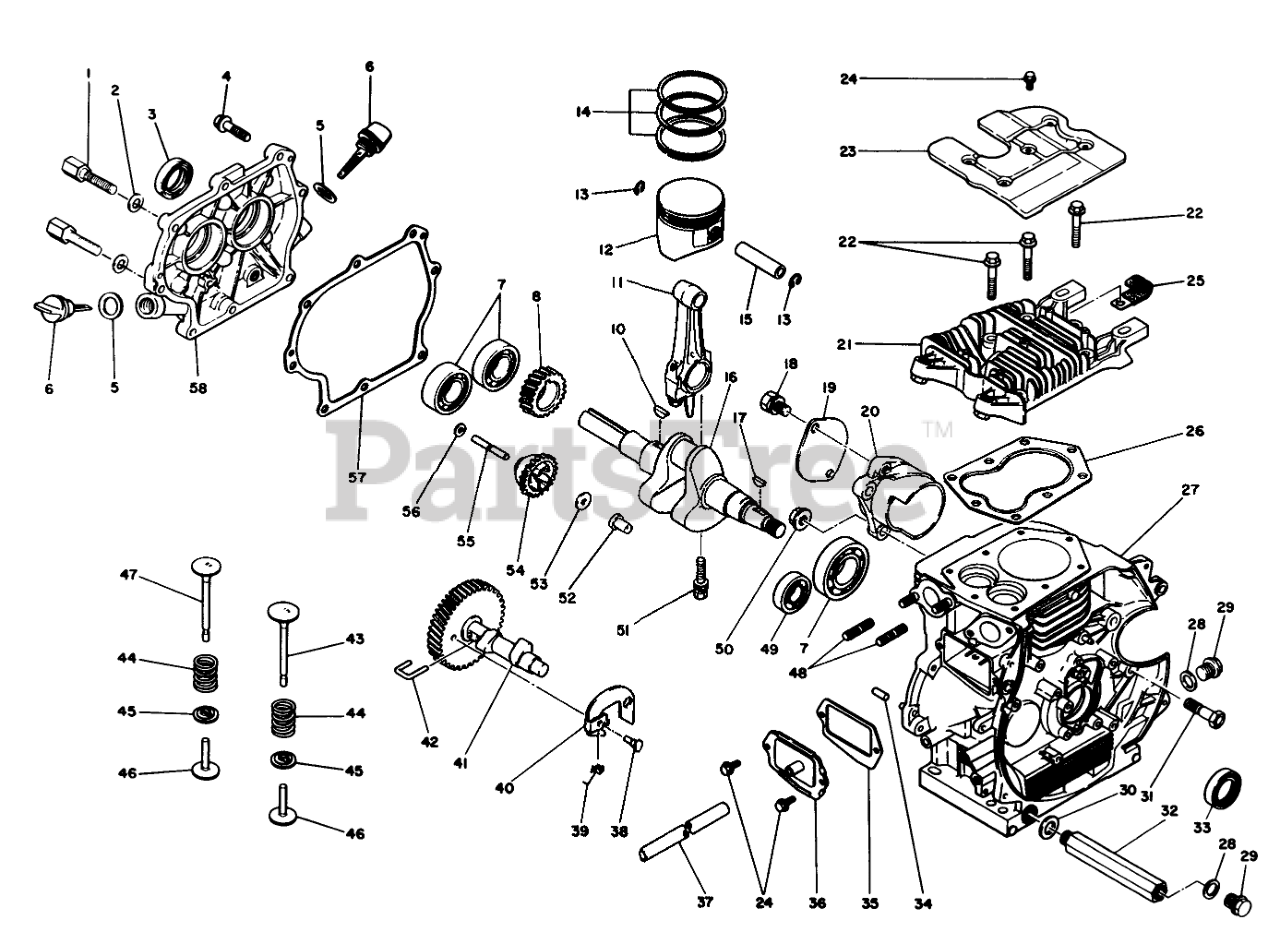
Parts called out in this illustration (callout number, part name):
2	WASHER
3	OIL SEAL
5	GASKET
6	Gauge-Oil (Incl. Ref. #5)
7	BEARING
8	CRANKSHAFT GEAR
11	Connecting Rod Assembly (Std.)(Incl. Ref #51)
12	Piston Assembly (Std.)(Incl. Ref. #15)
13	PISTON PIN CLIP
14	PISTON RING SET
15	PISTON PIN
16	CRANKSHAFT
18	BOLT & WASHER
19	COVER
20	BRACKET
21	CYLINDER HEAD
23	COVER-HEAD
25	CLAMP
26	HEAD GASKET
27	Cylinder Block Assembly (Incl. Ref. #34 & 48)
28	GASKET
29	DRAIN PLUG
30	GASKET
32	NIPPLE
33	OIL SEAL
35	GASKET=BRTHR
36	BREATHER VALVE ASM
37	BREATHER TUBE
39	SPRING
40	FLYWEIGHT
41	Camshaft Assembly (Incl. Ref. #38, 39, 40 & 42)
43	INT VALVE
44	VALVE SPRING
45	RETAINER VALVE
46	TAPPET
47	EXHAUST VALVE
49	BEARING
50	Nut-Flange
51	CONNECTING ROD BOLT
52	SLIDER-GOV
53	SPACER
54	Governor Gear Assembly (Incl. Ref. #52)
55	SHAFT-GOV.
56	WASHER
57	CRANKCASE GASKET
58	CRANKCASE COVER
